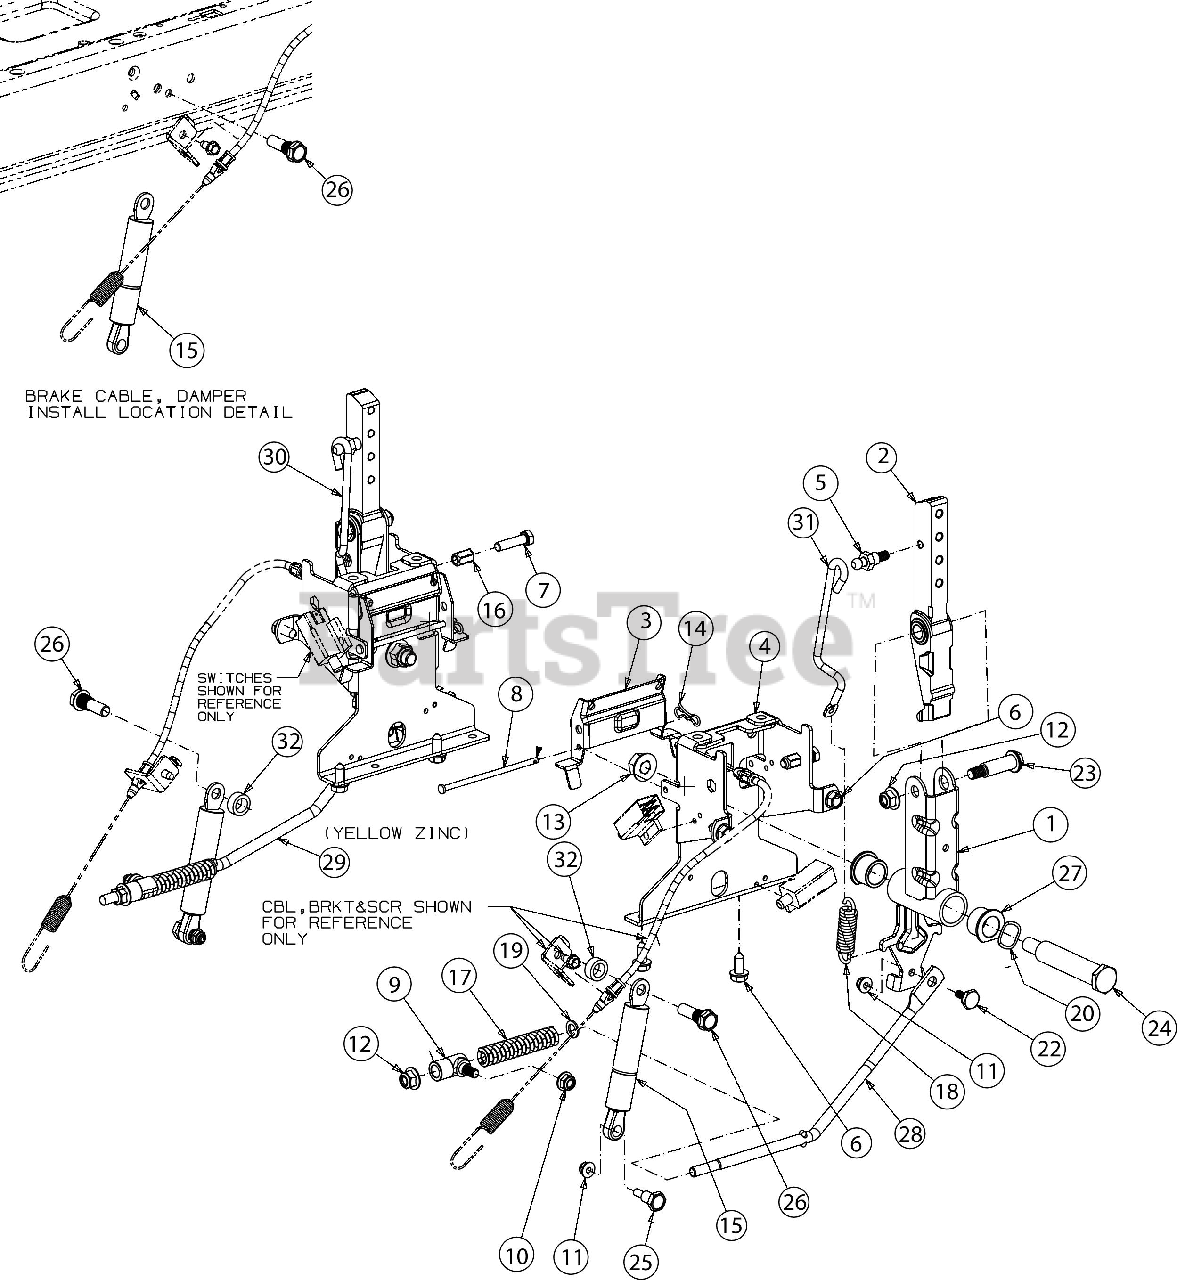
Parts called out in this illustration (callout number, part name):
1	LAPBAR PIVOT HUB
2	LOWER ARM ASSEMBLY
3	BRAKE CABLE LEVER
4	LAPBAR PIVOT SUPPORT
5	SCREW 5/16-18 X .48
6	SCREW 5/16-18 X .750
7	SCREW 5/16-18 X 1.25 GR5
8	PIN .188 X 4.1
9	SHOULDER FERRULE 3/8 ID X .420
10	FLANGE LOCK NUT 5/16-18
11	FLANGE LOCK NUT
14	BOW TIE COTTER PIN 1/4-5/16
15	DAMPNER CYLINDER
16	LOCK NUT RIVET 5/16-18
17	COMPRESSION SPRING .690 OD X 3.215 LG
18	EXTENSION SPRING
19	FLAT WASHER
20	WAVE WASHER .785X1.00X.012
22	SHOULDER SCREW
23	SHOULDER BOLT .498 DIA X 1.296 LG
24	SHOULDER BOLT .750 DIA X 3.25 LG
25	SHOULDER BOLT .395 DIA X .56 LG
26	SHOULDER BOLT .395 DIA X.83 LG DOG
27	FLANGE BEARING
28	HYDRO CONTROL ROD (RH)
29	HYDRO CONTROL ROD (LH)
30	LAPBAR DETENT ROD (LH)
31	LAPBAR DETENT ROD (RH)
